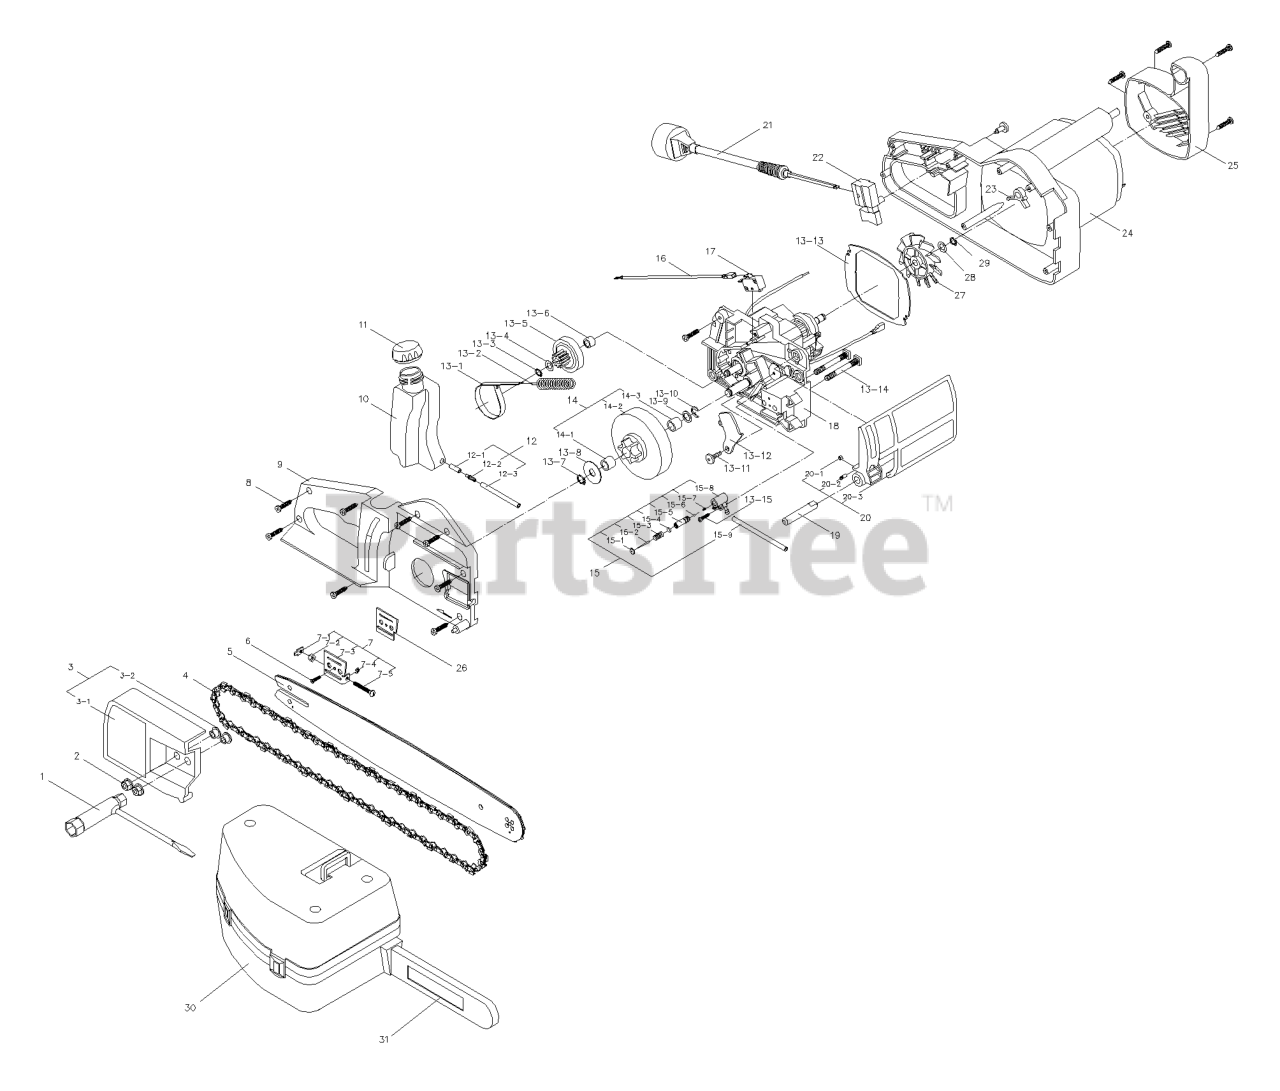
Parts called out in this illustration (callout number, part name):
3	CHAIN COVER ASS'Y
4	16" CHAIN
7	BAR ADJUSTMENT ASS'Y
9	HOUSING (R)
10	LUBRICANT TANK (FOR CHAIN)
11	TANK'S COVER
12	PIPE ASS'Y
13	TRANSMISSION ASS'Y
14	INNER GEAR ASS'Y
15	LUBRICANT PUMP ASS'Y
16	CONDUIT ASS'Y
17	MICRO-SWITCH
19	BRAKE'S SHAFT
20	BRAKE'S POLE ASS'Y
21	POWER CORD
22	SWITCH
23	POLE FOR BRAKE'S MICRO-SWITCH
24	HOUSING (L)
25	REAR COVER
26	OIL WASHER
30	CARRY CASE
